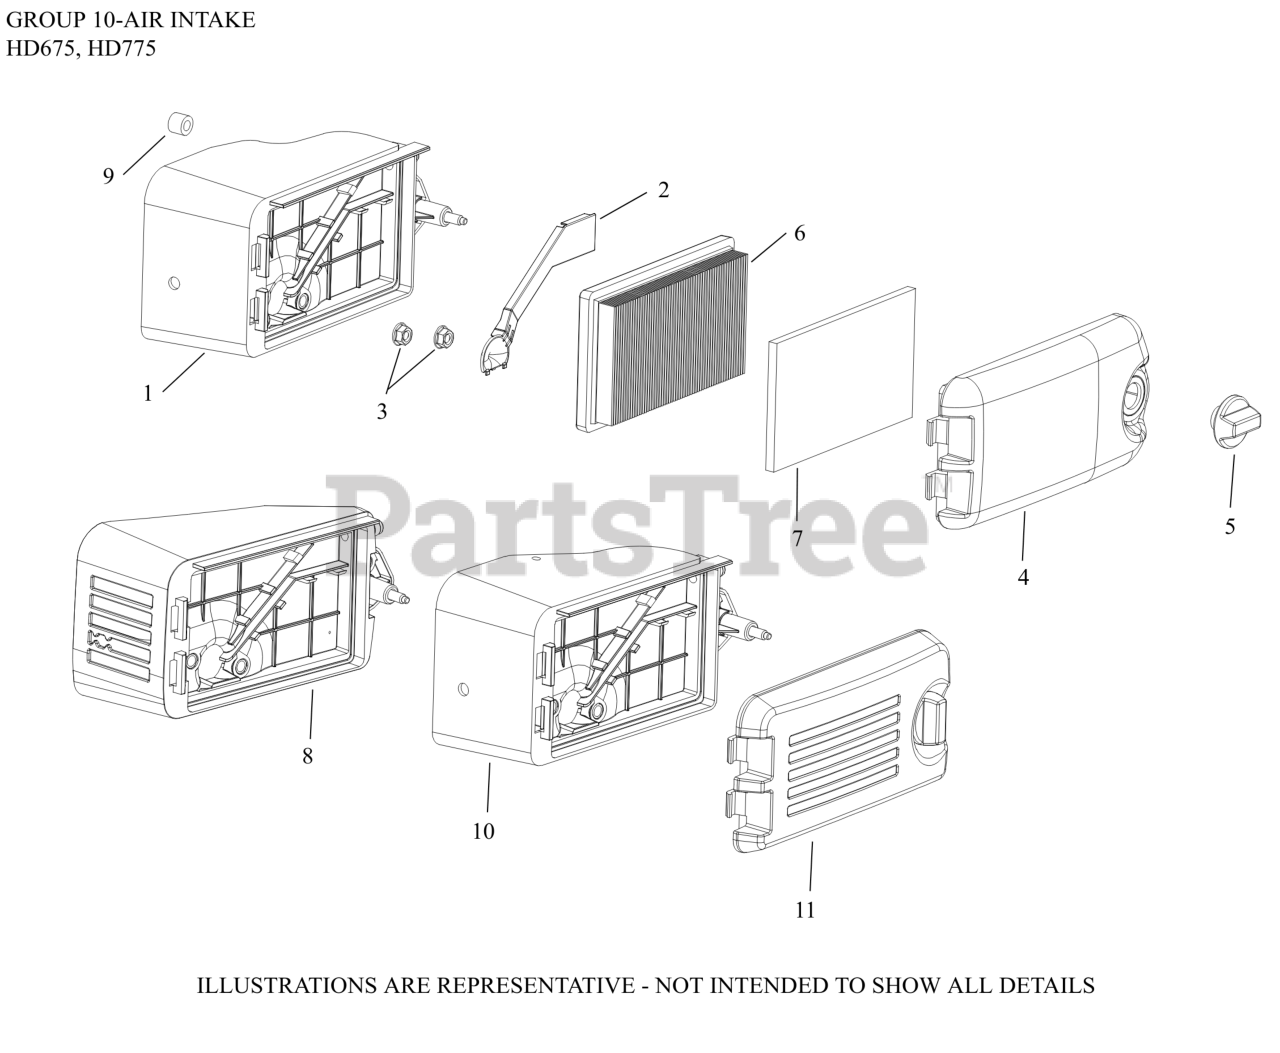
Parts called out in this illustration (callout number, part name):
1	AIR CLEANER BASE-USE 14 094 23-S
2	COVER, A/C BASE (BREATHER GAS)
4	COVER, AIR CLEANER
5	KNOB, AIR CLEANER
6	ELEMENT, AIR FILTER
7	ELEMENT, PRE-CLEANER
9	SPACER, AIR CLEANER BASE
12	GASKET, AIR CLEANER BASE
